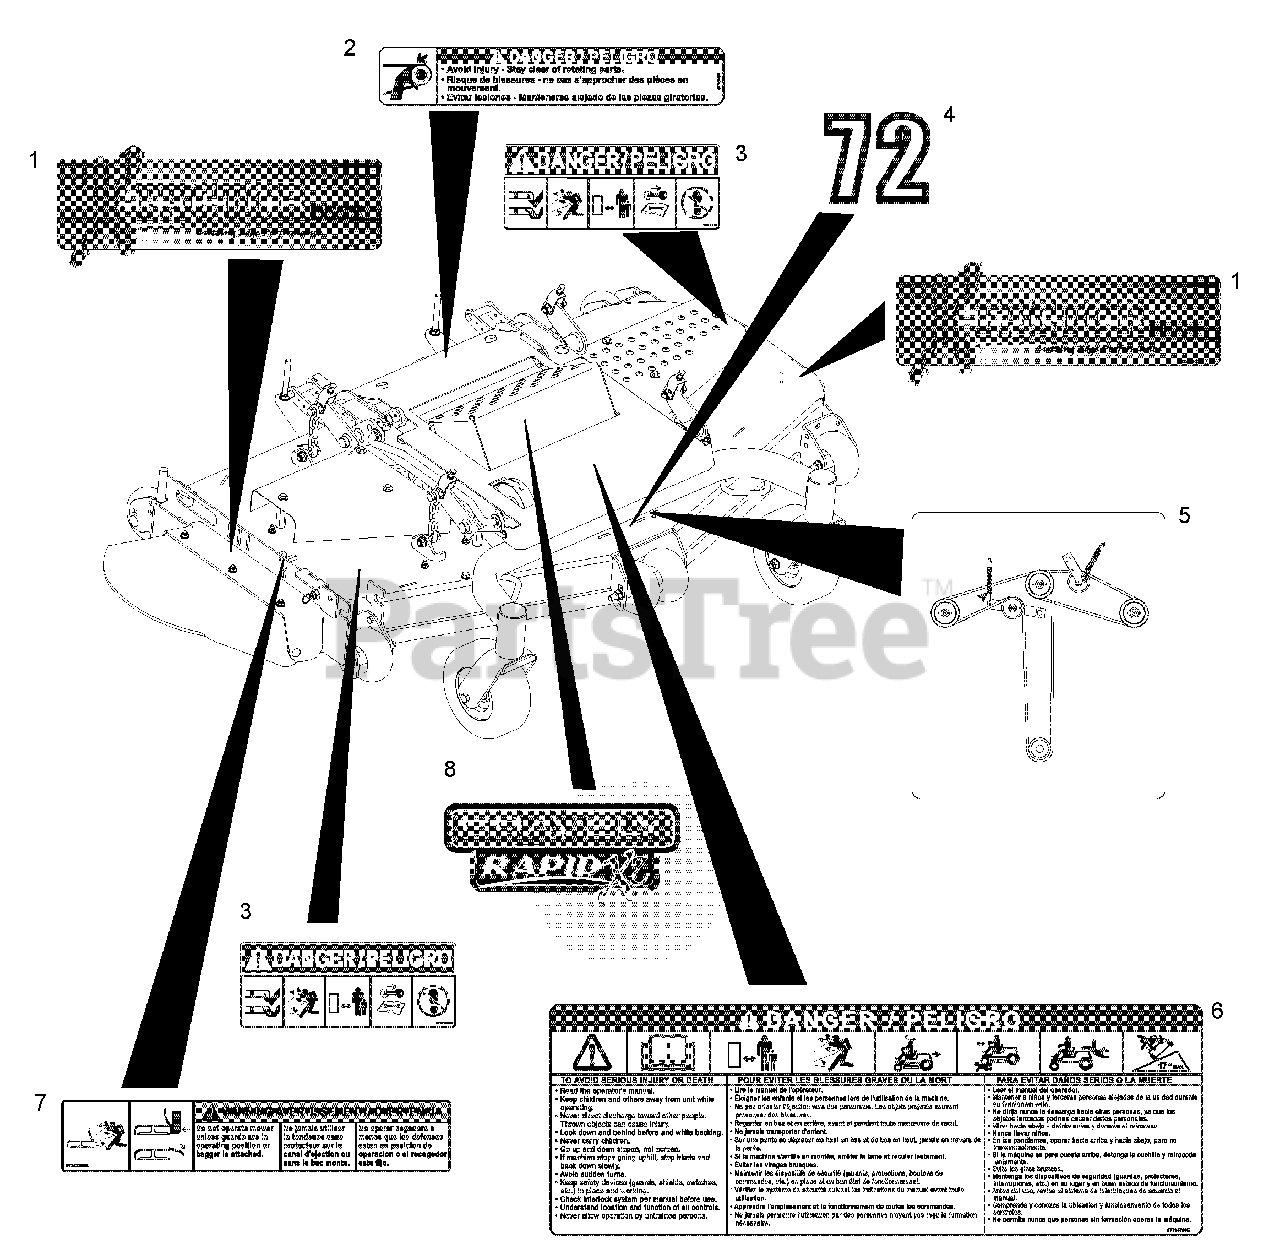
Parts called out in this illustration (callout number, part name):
1	Decal, X-Factor
2	Decal, Danger Rotating Parts
3	Decal, Mower Pan Danger
4	Decal, 72
5	Decal, Belt Diagram
6	Decal, Warning
7	Decal, Warning
8	Decal, Gravely Rapid XZ
